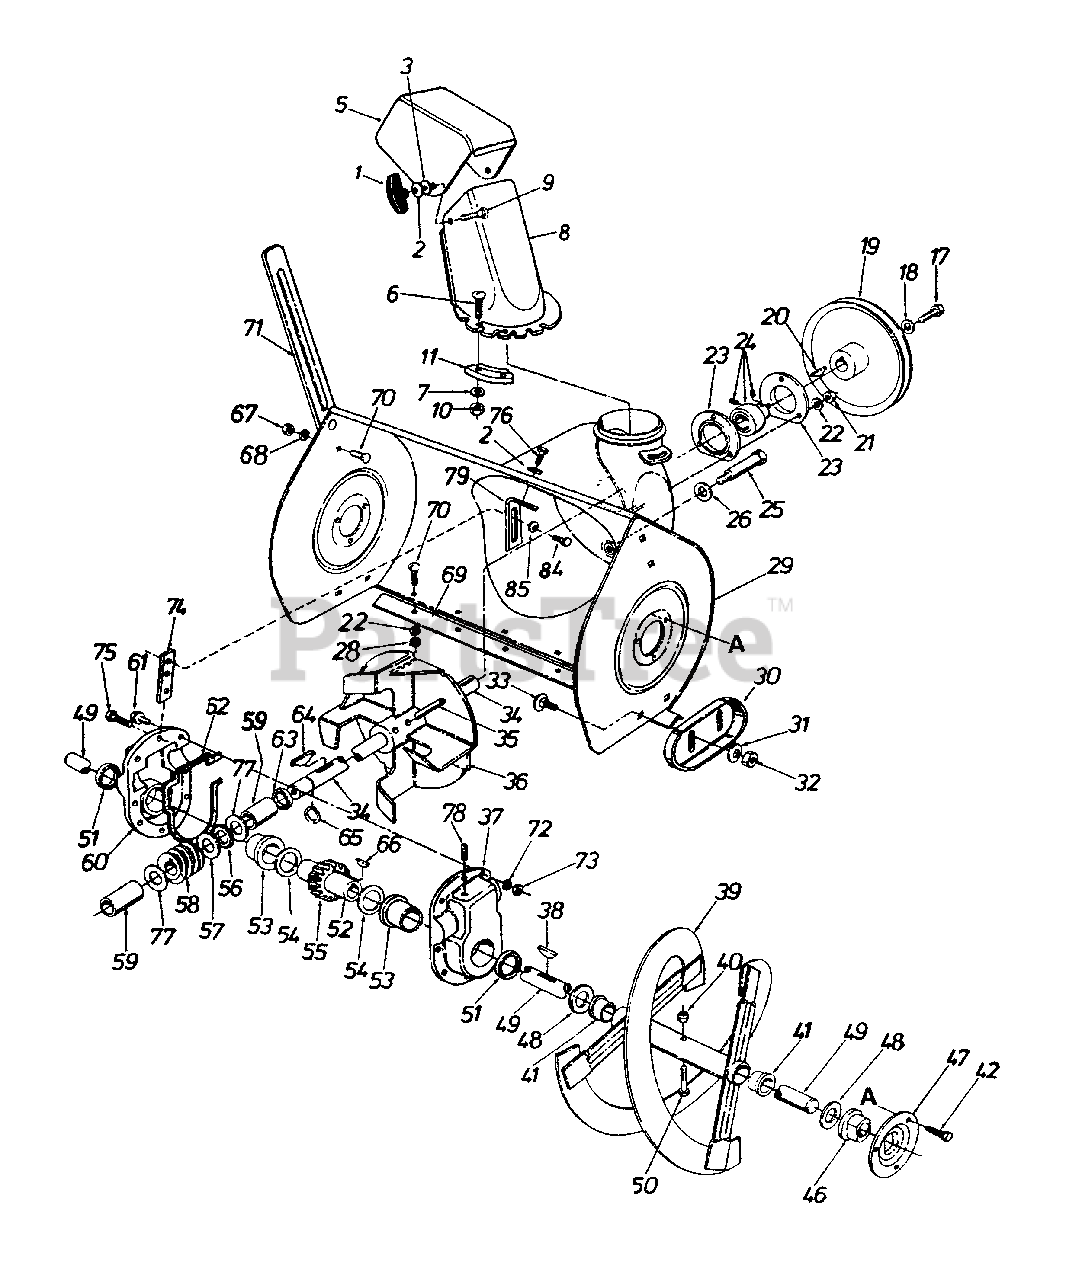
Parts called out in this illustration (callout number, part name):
1	Handle Knob Assembly
2	Bell. Washer .345 I.D. x .88 O.D. x .06
3	Flat Washer .344 I.D. x 1.125 O.D. x .125
5	Upper Black Plastic Chute
6	Truss Mach Scr 1/4-20 x .75
7	Flat Washer .281 I.D. .50 O.D. x .063
8	Lower Black Plastic Chute
9	Carriage Bolt 5/16-18 x 1.00" Lg.
10	Hex . Cent. L-Nut 1/4-20
11	Chute Flange Keeper
17	Hex Screw 5/16-18 x .88
18	Bell. Washer .345 I.D. x .88 O.D. x .06
19	1/2" V-Pulley .875 I.D. x 10.12 O.D.
20	#9 Hi-Pro Key 3/16 x 3/4 Dia. HT
21	Hex Nut 5/16-18
22	L-Wash 5/16 I.D.
23	Bearing Housing
24	Self-Aligning Bearing .875 I.D.
25	Belt Keeper Studs 3/8-16 x 2.75
26	Bell-Washer .400 I.D. x .88 O.D. x .06
28	Hex Nut 5/16-18
31	Bell-Washer .400 I.D. x .88 O.D. x .06
32	Hex Jam Nut 3/8-16
33	Carriage Bolt 3/8-16 x .62" Lg.
34	Blower Axle
35	Spring Spiral Pin Heavy 5/16 Dia. x 1.7
38	#91 Woodruff Key 1/4 x 3/4 Dia.
39	Spiral Ass'y. L.H. - 33"
39	Spiral Ass'y. R.H. - 33"
40	Hex Ins. L-Nut 5/16-18
41	Plastic Bushing
42	Hex Wash. HD AB Tap Scr. 5/16 x .75
46	Flange Bearing w/Flats
47	Bearing Housing
48	Flat Washer
49	Spiral Axle - 30"
49	Spiral Axle - 33"
50	Shear Bolt 5/16-18 x 1.75
51	Oil Seal 1.50 I.D. Garlock (76 x 6223)
52	Worm Gear Shaft
53	Flange Bearing
54	Flat Washer 1.5 I.D. x 2.0 O.D. x .03
55	Double Threaded Worm Gear
56	Thrust Bearing .88 I.D. x 1.44 O.D. x .078
57	Flat Washer .88 I.D. x 1.4 O.D. x .125
58	Worm Gear L.H. Double Thread
59	Sleeve Bearing .875 I.D.
60	Gear Housing Half - R.H.
61	Hex Scr. 5/16 x 1.00
62	Cork & Rubber Gasket
63	Oil Seal for .875 I.D. Garlock (76 x 6133)
64	#9 HI-Pro Key 3/16 x 3/4 Dia. HT
65	Snap Ring for .875 Dia. Shaft
66	#91 Woodruff Key 1/4 x 3/4 Dia.
67	Hex Nut 5/16-18 Optional Parts
68	L-Wash. 5/16 I.D. Optional Parts
70	Carr. Bolt 5/16 x 18 x .62" Lg. Optional Parts
72	Shakeproof Spring Washer
73	Hex Ins. L-Nut 5/16-18
74	Gear Housing Support Plate 1 x 3/16
75	Hex Bolt 5/16-18 x 1.25
76	Hex Wash. HD AB Tap Scr. 5/16 x .75
77	Flat Washer .88 I.D. X 1.4 O.D. x .125
78	Plastic Vented Plug 1/4-18 Pipe Thread
80	Carriage Bolt 5/16-18 x .75
84	Hex Scr. 1/4-28 x .75
85	Bell. Washer.25 I.D. x .88 O.D. x .062
85	Worm Gear Box Ass'y.
05139A-0637	BLADE-GUIDE (DRIFT - POWDER BLACK (0637)
05139A-0638	BLADE-GUIDE (DRIFT - MTD/TROY-BILT RED (0638)
05139A-0662	BLADE-GUIDE (DRIFT - OYSTER GRAY (0662)
05139A-0665	BLADE-GUIDE (DRIFT - YARDMAN GREEN (0665)
05139A-0674	BLADE-GUIDE (DRIFT - YARDMAN YELLOW (0674)
05139A-0716	BLADE-GUIDE (DRIFT - CUB YELLOW-99 (0716)
